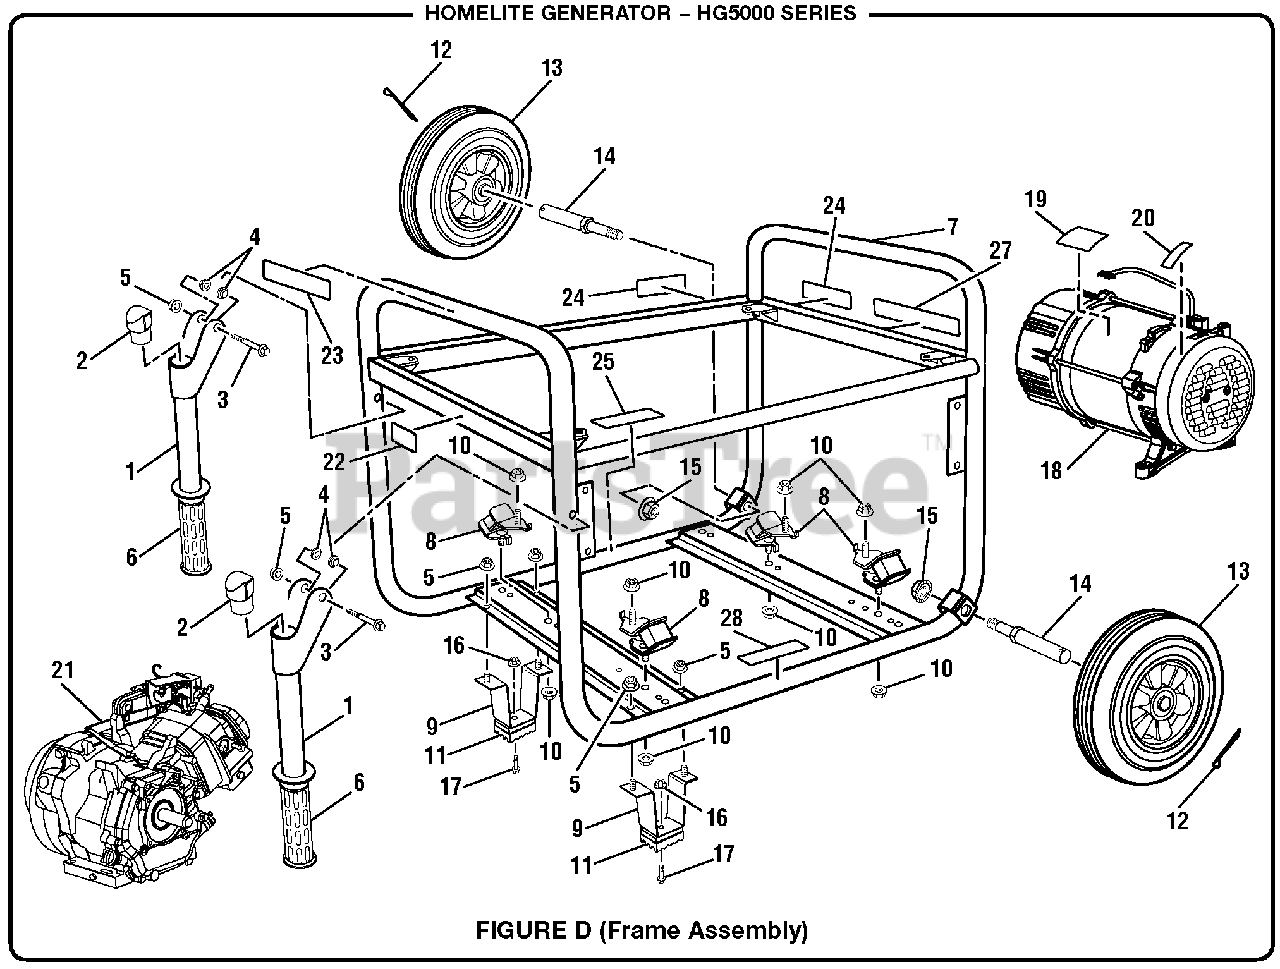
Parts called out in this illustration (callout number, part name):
1	Handle Bar Assembly
2	Handle Bar Plug
3	Bolt (M8 x 45 mm)
4	Handle Bar Insert
6	Handle Grip
8	Motor Mount
9	Foot, Bracket
10	Nut (M10)
11	Rubber Foot
12	Cotter Pin (3 mm)
13	Wheel (10 in.)
15	Nut (M12, Flange Hd.)
16	Flange Nut (M6)
17	Screw (M6 x 25)
18	Generator Head Assembly
19	Data Label
20	Ground Label
22	Fuel Valve Label
23	Combustion Label
24	Hot Surface Warning Label
25	Fire Danger Label
26	Ground Warning Label
27	Lubricant Label
